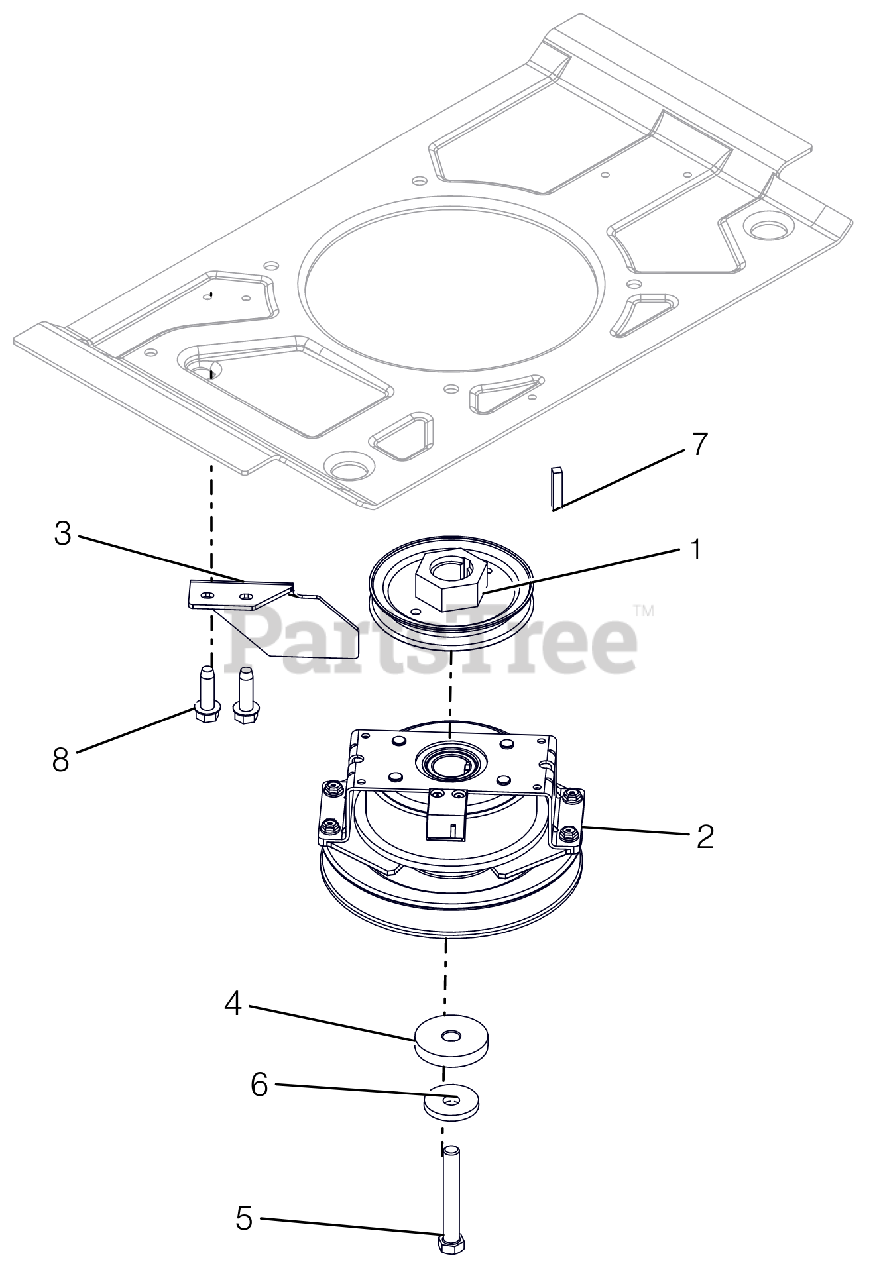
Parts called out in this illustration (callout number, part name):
1	WLDMT,PULLEY-4.50ODX1.003
2	CLUTCH, OGURA DBL SPRG
3	BRKT, CLUTCH STOP HD
4	SPACER, .474/.459X2.00X.350
5	BLT-HEX .44-20X3 G8YZ NYTORQ
6	WASHER, 7/16" SPRING DISK
7	KEY-SQ .25 X 1.25 X .25 SAE
8	@SCR-TAP .38-16X1.25 HWH TR YZ
